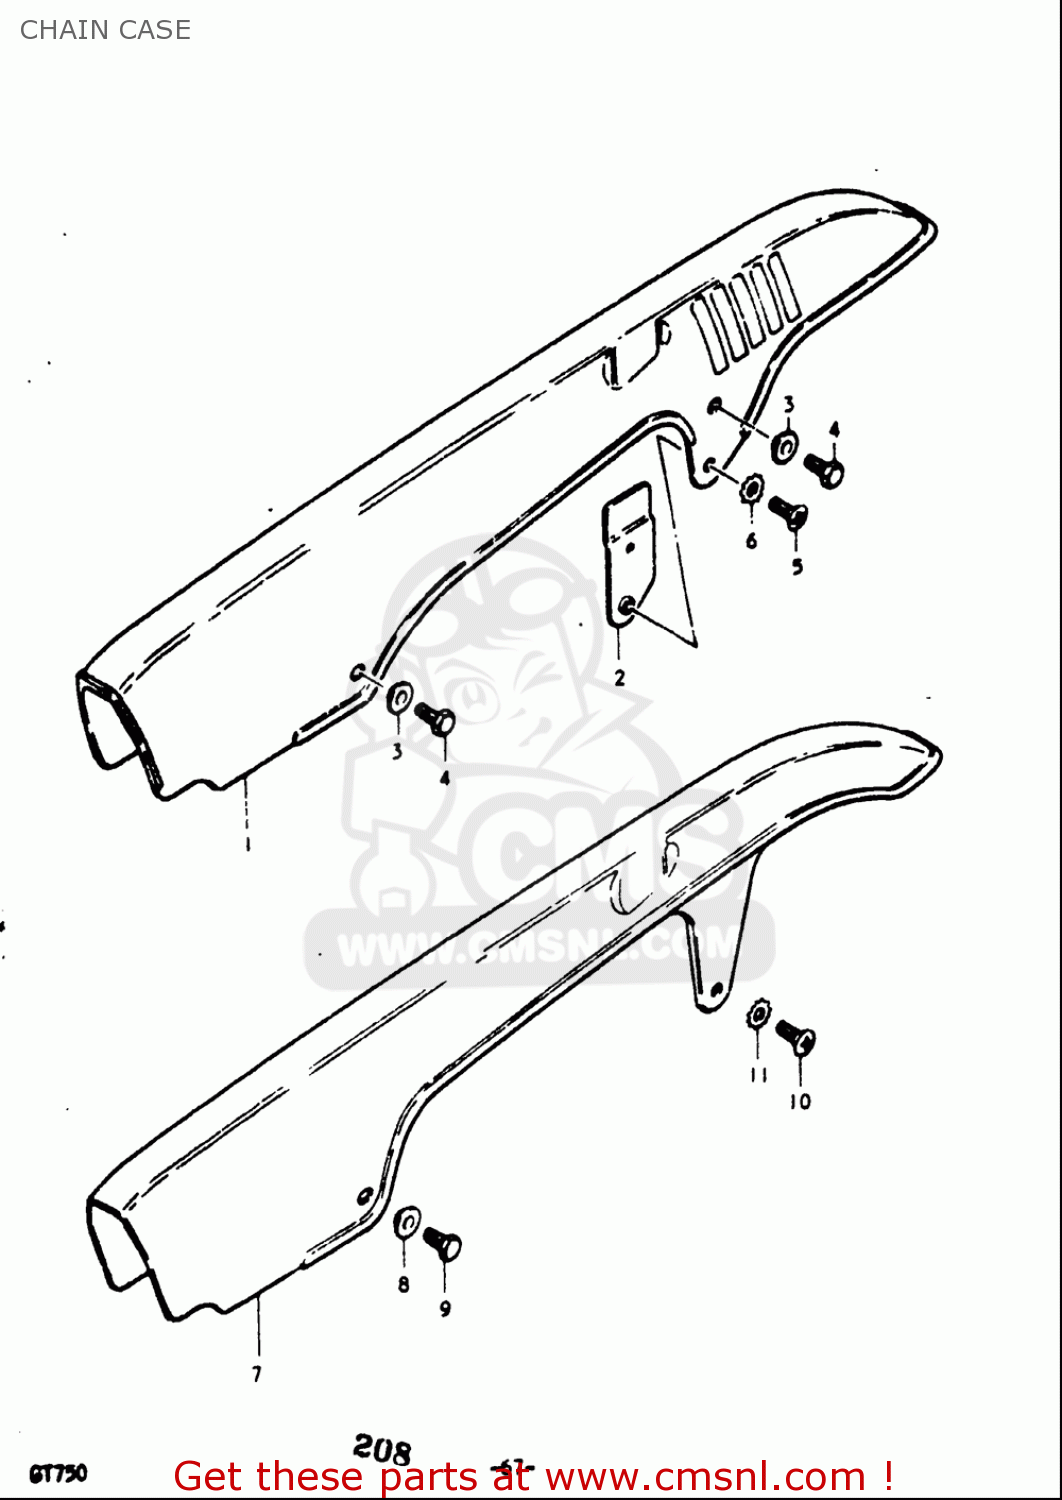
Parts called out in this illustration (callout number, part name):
3	WASHER
4	BOLT(6X8)
5	SCREW
6	LOCK WASHER
7	CASE,CHAIN
8	WASHER(6.5X18X1.6)
9	BOLT(6X8)
10	SCREW
11	LOCK WASHER
